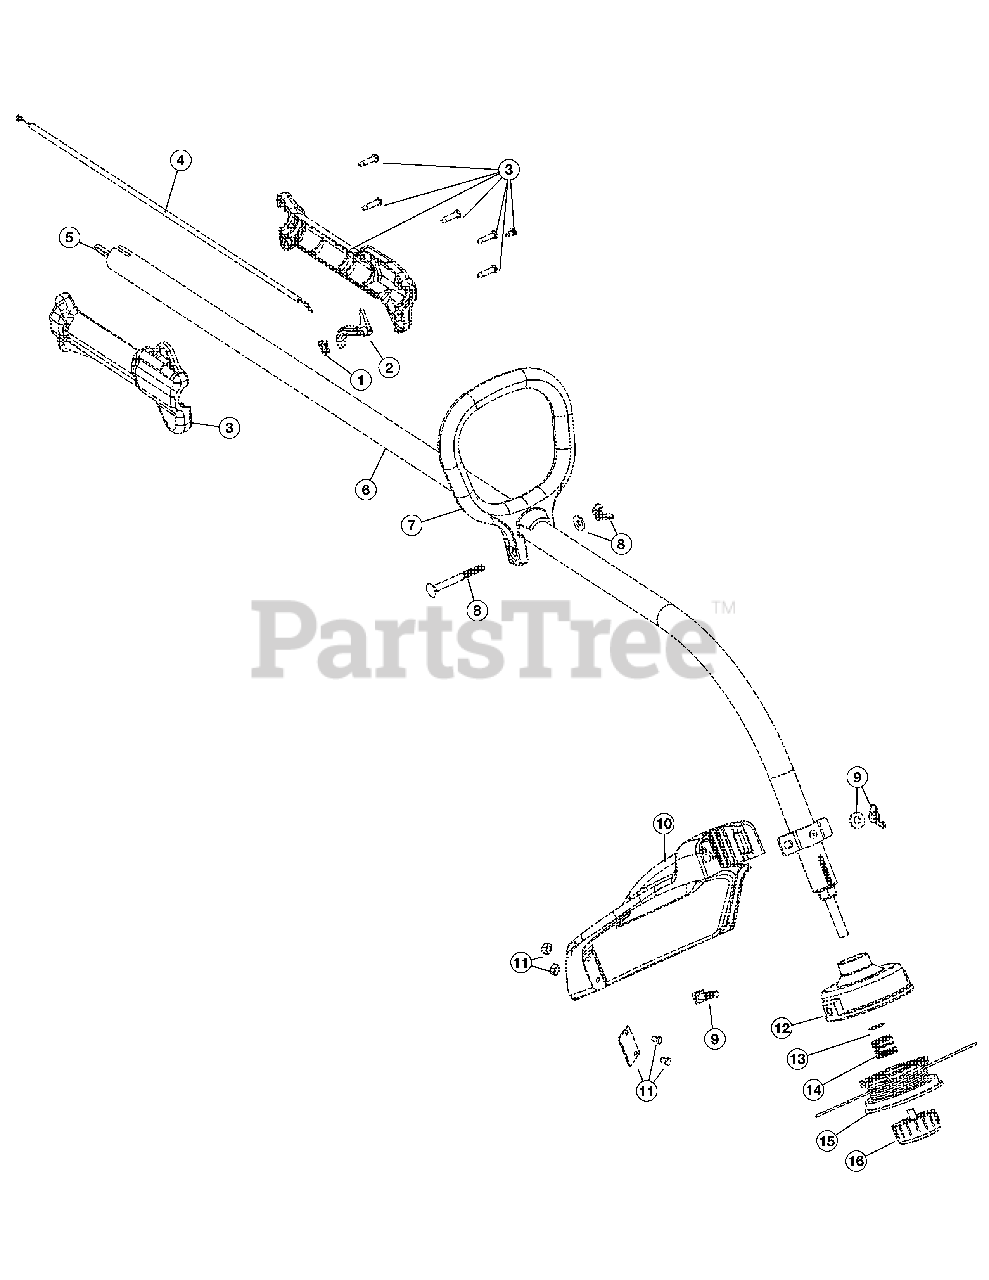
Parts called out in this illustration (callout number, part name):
1	Throttle Trigger Spring
2	Throttle Trigger
3	Throttle Housing Assembly (includes 1 & 2)
4	Throttle Cable
5	Flexible Drive Shaft
6	Drive Shaft Housing (includes 13)
7	D-Handle Assembly (includes 8)
8	D-Handle Hardware
9	Guard Mounting Hardware
10	Guard (includes 11)
11	Blade Assembly
12	Outer Reel (includes 13)
13	Retainer
15	Inner Reel
16	Bump Knob
